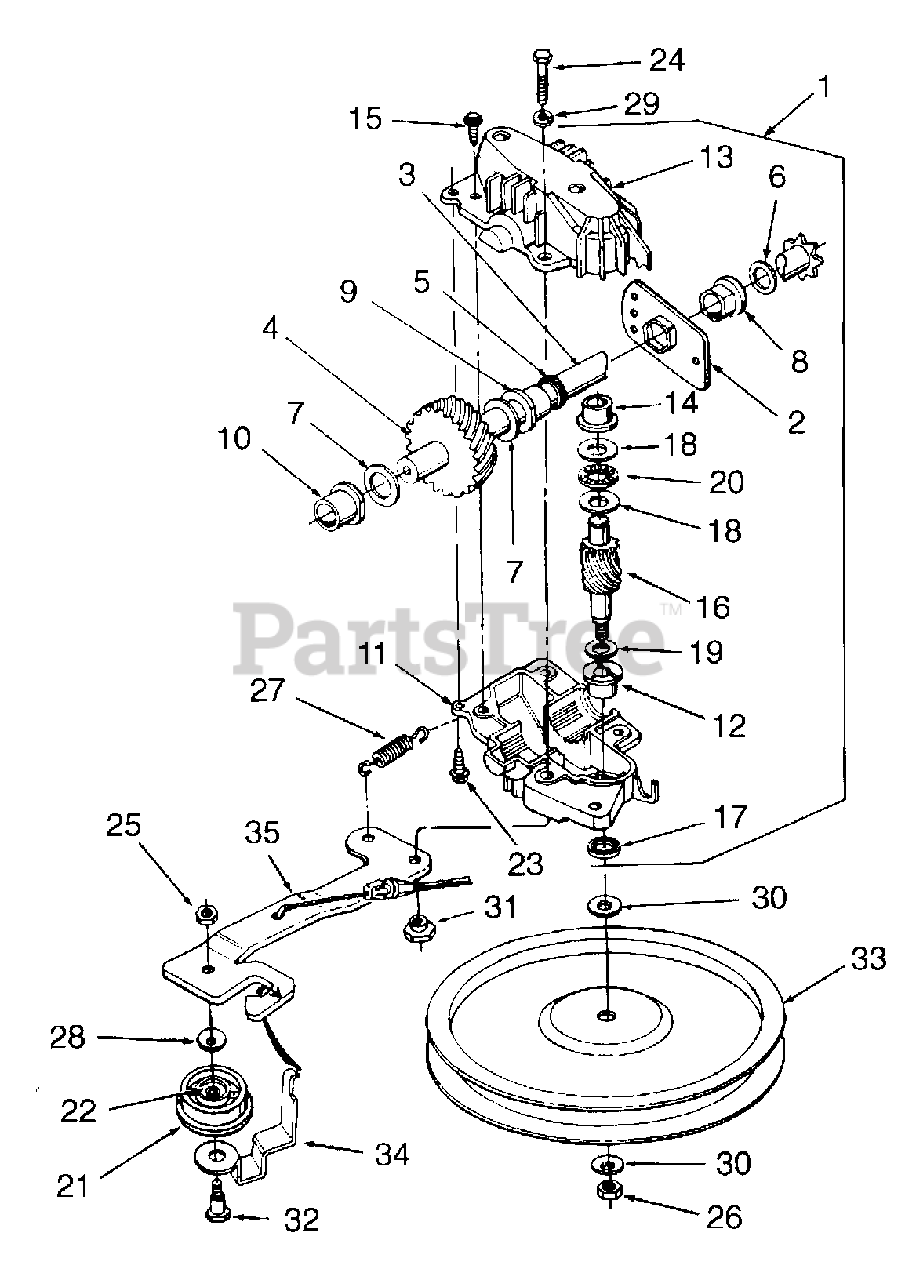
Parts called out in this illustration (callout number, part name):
1	Transmission Assembly, Complete
3	Shaft, Output w/6T Sprocket
4	Gear, Helical 34T
5	Seal, Oil, .625 x .812
6	Washer, Flat, .64 x 1.24 x .06 HD
7	Washer, Flat, 5/8 x 1.0
8	Bearing, Hex Flange, .631 ID
9	Bearing, Flange, .629 ID
10	Bearing, Flange, .566 ID
11	Housing, Lower
12	Bearing, Flange, .503 ID
13	Housing, Upper
14	Bearing, Flange, .378 ID
15	Screw, Hex Tapp, #10-16 x .75
16	Shaft, Pinion 10T
17	Seal, Oil, .50 x .687
18	Washer, Thrust, .382 x .684
19	Washer, Flat, .504 x .70 x .030
20	Bearing, Thrust, .375 x .812
21	Pulley Ass'y, Idler w/Bearing
22	Bearing, Needle, .375 x .375
23	Screw, Hex Tapp, #10-16 x .75
24	Screw, Hex w/Patch, 1/4-20 x 1.25
25	Nut, Hex, 1/4-28
26	Nut, Hex Jam, 5/16-24 L.H. Thd
27	Spring, Extension, 1.12 Lg
28	Washer, Bell, .265 x .75 x .06
29	Washer, Lock, 1/4
30	Washer, Bell, .325 x .930 x .045
31	Shoulder Spacer, .375 x .165
32	Shoulder Bolt, 1/4-28 x .375
33	Pulley, Flat, 5.06 Dia
34	Belt Keeper
35	Bracket, Idler
